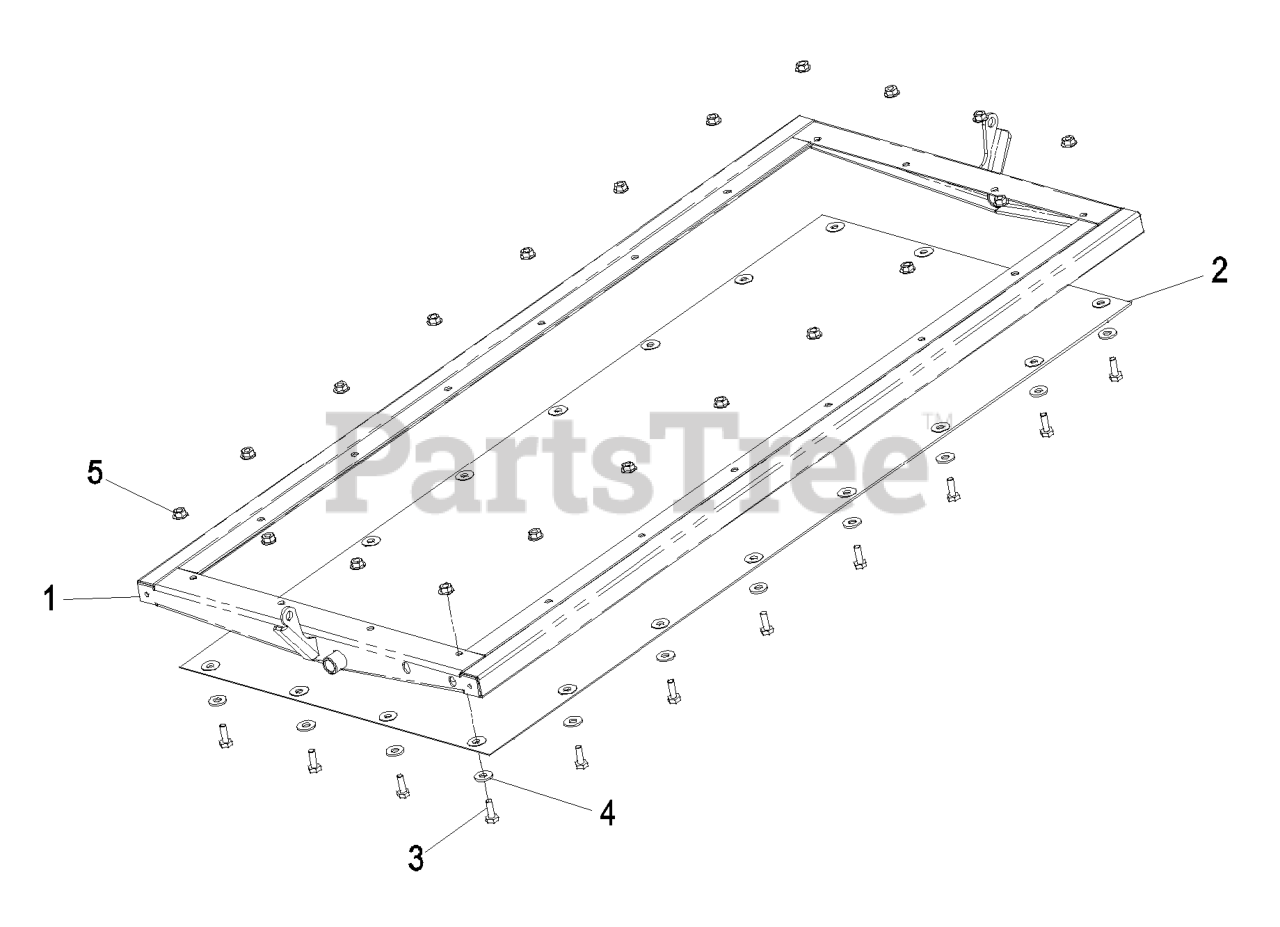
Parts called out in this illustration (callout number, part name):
1	DOOR-FRAME
2	SCREEN-DOOR
3	SCREW-HH
4	WASHER-FLAT
